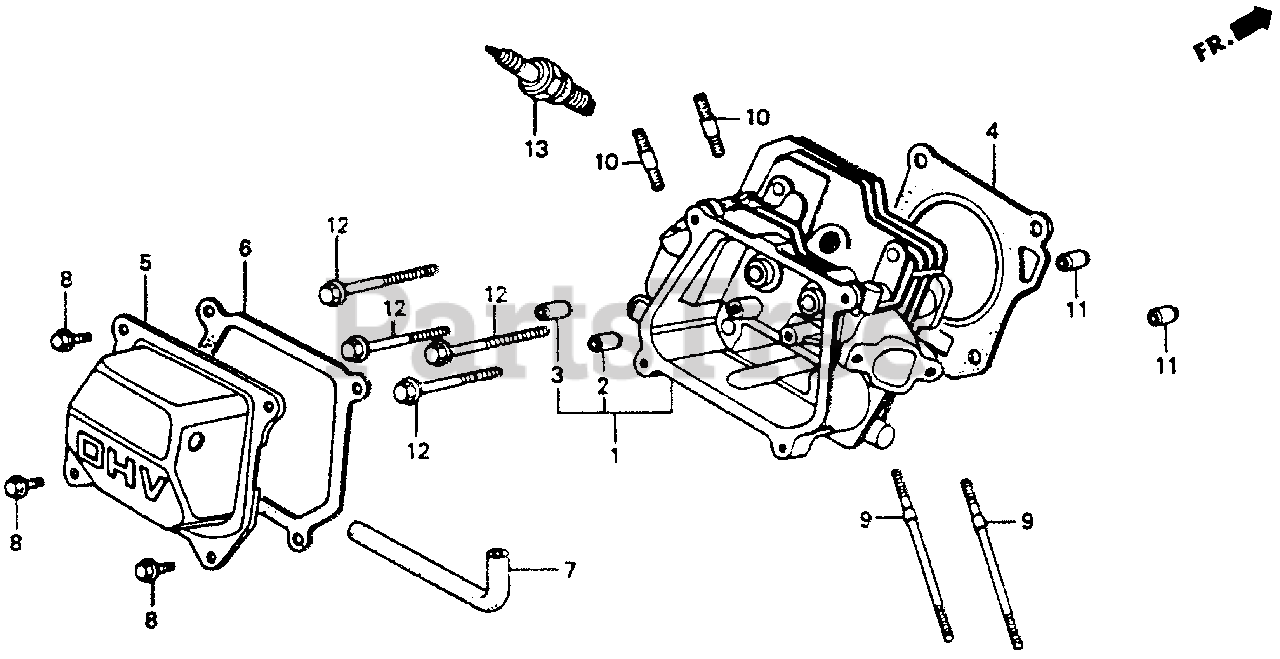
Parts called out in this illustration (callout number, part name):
1	CYLINDER HEAD (NOT AVAILABLE)
1	CYLINDER HEAD
2	GUIDE, VALVE (OS)
3	GUIDE, EX. VALVE (OS)
4	GASKET, CYLINDER HEAD
5	COVER, HEAD
6	GASKET, HEAD COVER
7	TUBE, BREATHER
8	BOLT, FLANGE (6X12) (CT200)
8	BOLT, FLANGE (6X13) (CT200)
9	BOLT, STUD (6X112)
10	BOLT, STUD (8X32)
11	PIN, DOWEL (10X16)
12	BOLT, FLANGE (8X60)
13	SPARK PLUG (BPR6ES) (NGK)
13	SPARK PLUG (W20EPR-U) (DENSO)
